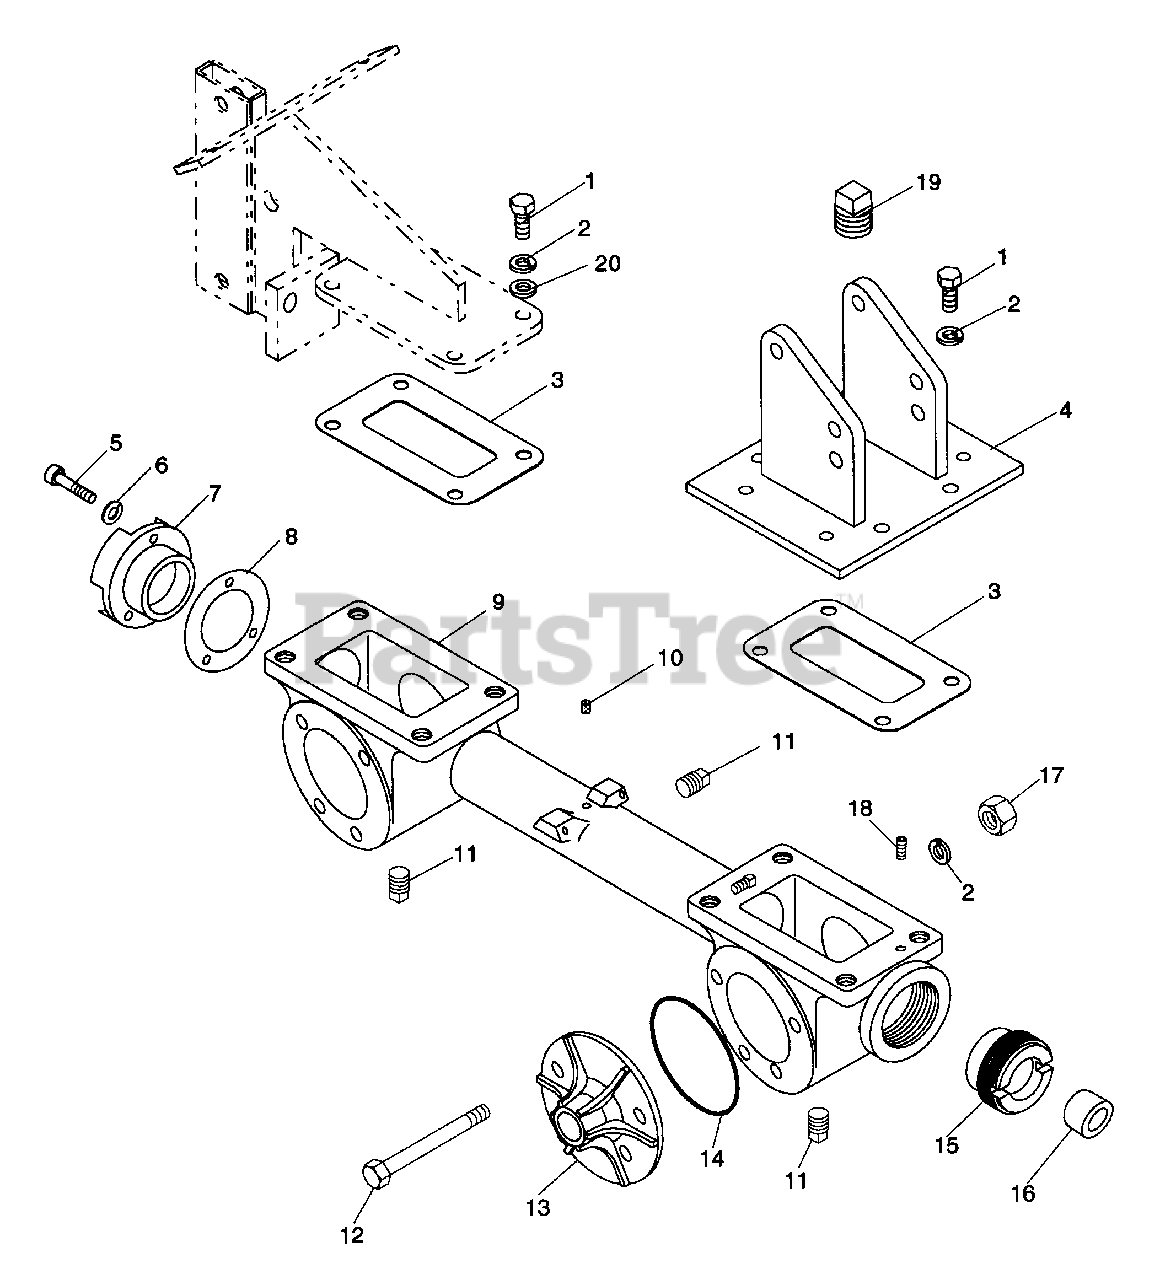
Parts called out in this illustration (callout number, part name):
1	BLT-HEX .31-18X.75 PL GR2
2	WSHR-LK .312X.097 PL HVY
4	HANDLEBAR MOUNT
5	SCR-SKH .25-20X.75 PL
6	WSHR-LK .250X.077 HVY PL
7	REAR CAP
8	GASKET - REAR CAP
9	GEAR CASE
10	BREATHER
11	PIPE PLUG, 1/4 NPT
12	BLT-HEX .31-18X3.50 PL GR2
13	AXLE HOUSING
14	O-RING 3.625X3.875X.135
15	ADJUSTMENT PLUG
16	SEAL .750X1.250X.136
17	NUT-HEX .312-18
18	SCR-SET .25-20X.25 SKHCUPNY OH
19	PIPE PLUG
20	WSHR-FL-STL .323X.625X.062 PL
